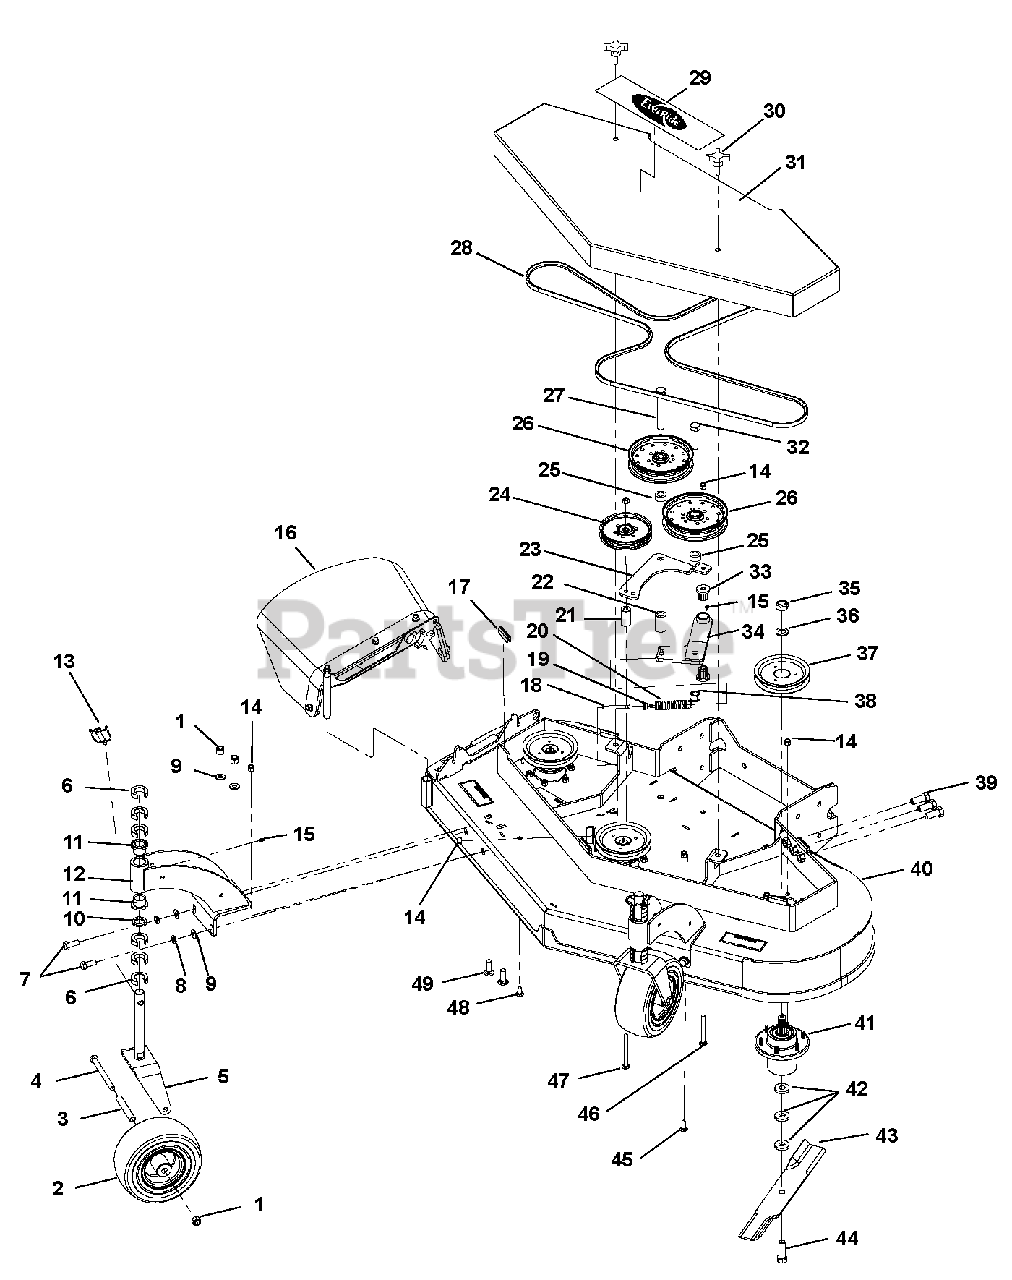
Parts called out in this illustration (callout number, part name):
1	Nut, Lock .50-13 Nylon
2	Assembly, Wheel & Tire - 9 x 3.5-4
3	Tube, Caster Axle
4	Bolt, .50-13 x 5.50 Hex Grade 5
5	Weldment, Caster Yoke
6	C-Spacer, 1.00 x 1.77 x .50
7	Bolt, .50-13 x 1.25 Hex Grade 5
8	Washer, Lock .50 x .125 Regular
9	Washer, Flat .50 x 1.25 x .083
10	Bushing, 1.03 x 1.50 x .179
11	Bearing, Flange 1.00 x 1.25 x 1.00
12	Weldment, Strut Front FXWLK
13	Pin, LNC .438 x 2.00
14	Nut, Lock .38-16 Nylon
15	Fitting, .25-28 Straight Grease Zerk
16	Assembly, Discharge Shield
17	Trim, 2" Trim-Lok Edge
18	Rod, Threaded Adjustment
19	Nut, .375-16 Spring Lock Flanged
20	Spring, External .875 x .125 x 4.25
22	Bushing, .688 x 1.13 x 1.89
23	Strap, Idler 52" FXWLK
24	Pulley, Flat 5.00 x .375 w/Bearing
25	Bushing, .688 x 1.13 x .55
26	Pulley, Flat 6.00 x .635 w/Bearing
27	Bolt, .62-11 x 4.50 Hex Grade 5
28	Belt, HB 124.0 Elbow AMD
29	Decal, 9" EverRide Logo Small
30	Knob, .375 x 1.25 - 4 Prong
31	Weldment, Belt Shield 52" FXWLK
32	Bolt, .62-11 x 2.50 Hex Grade 5
33	Bearing, Flange M10 x M25 x M27 Fluted
34	Weldment, Idler Arm FXWLK
35	Locknut, .75-16 Crown
36	Washer, .75 x 1.3125 x .113
37	Pulley, Spline Spindle Offset
38	Nut, Lock .625-11 Nylon
39	Bolt, .62-11 x 1.50 Hex Grade 8
40	Wasp w/Decals
41	Assy, Spindle Housing
42	Washer, Blade
43	Blade, 18"
44	Bolt, .62-11 x 2.00 Hex Grade 8
45	Bolt, .38-16 x 1.00 Round Head Square Neck Grade 5
46	Bolt, .38-16 x 3.50 Round Head Square Neck Grade 5
47	Bolt, .38-16 x 4.00 Round Head Square Neck Grade 5
48	Bolt, .38-16 x .75 Round Head Square Neck Grade 5
49	Bolt, .50-13 x 1.50 Round Head Square Neck Grade 5
